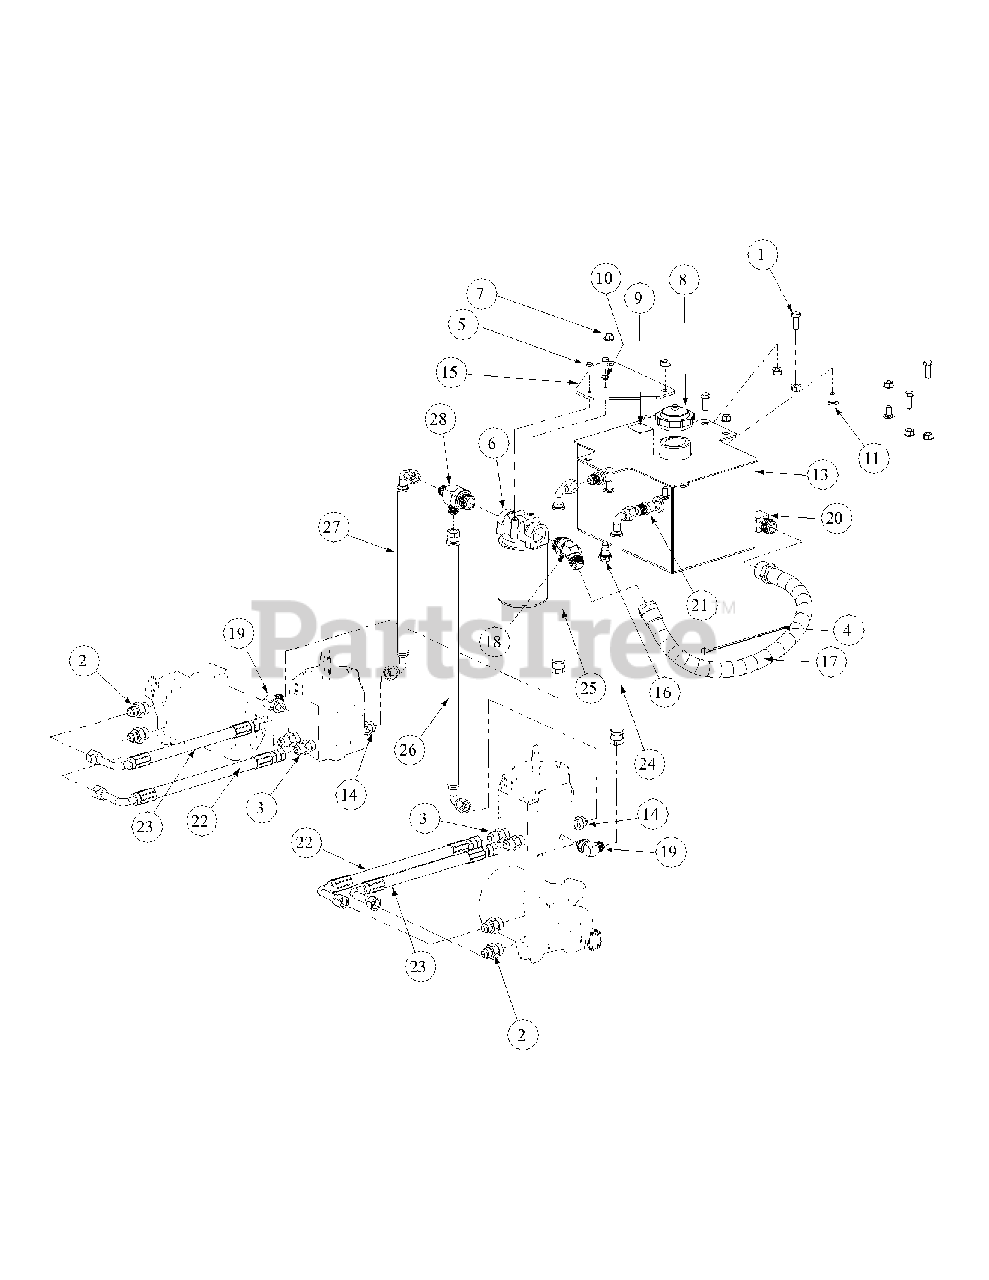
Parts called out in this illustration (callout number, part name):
1	Hex Cap Screw, 3/8-16, 1
2	Fitting 1/2 x 3/4 - O Ring
3	Fitting 1/2 x 3/4 - O Ring to Flare
4	Cable Tie, 3/16 x .05 x 7.4
5	Hex Cap Screw, 1/4-20, .75
6	Filter Head 3/4
7	Hex Nut Flange Lock, 3/8-16
8	Cap, Hydro Oil Tank
9	Decal Oil Only 20W50
10	Lock Washer, 1/4
11	Carriage Bolt, 3/8-16 x .75 LG.
13	Hydraulic Tank Assembly
14	Fitting Connector, 1/2 x 3/8
15	Oil Filter Mounting Plate
16	Oil Pan Drain w/ Seal and Plug
17	Tank to Filter Hose Assembly
18	Connector, 3/4 x3/4
19	Elbow Fitting, 3/8 O-ring, 1/2 Flare
20	Fitting Elbow, 1/2 x 1/2
21	Fitting, 3/8 NPT, 1/2 Flare
22	Long Pressure Hose Assembly
23	Short Pressure Hose Assembly
24	17.75" Return Hose Assembly, RH
25	14" Return Hose Assembly, LH
26	21.25" Supply Hose Assembly, RH
27	15.50" Supply Hose Assembly, LH
28	Tee Fitting, 3/4 x 1/2 x 1/2
